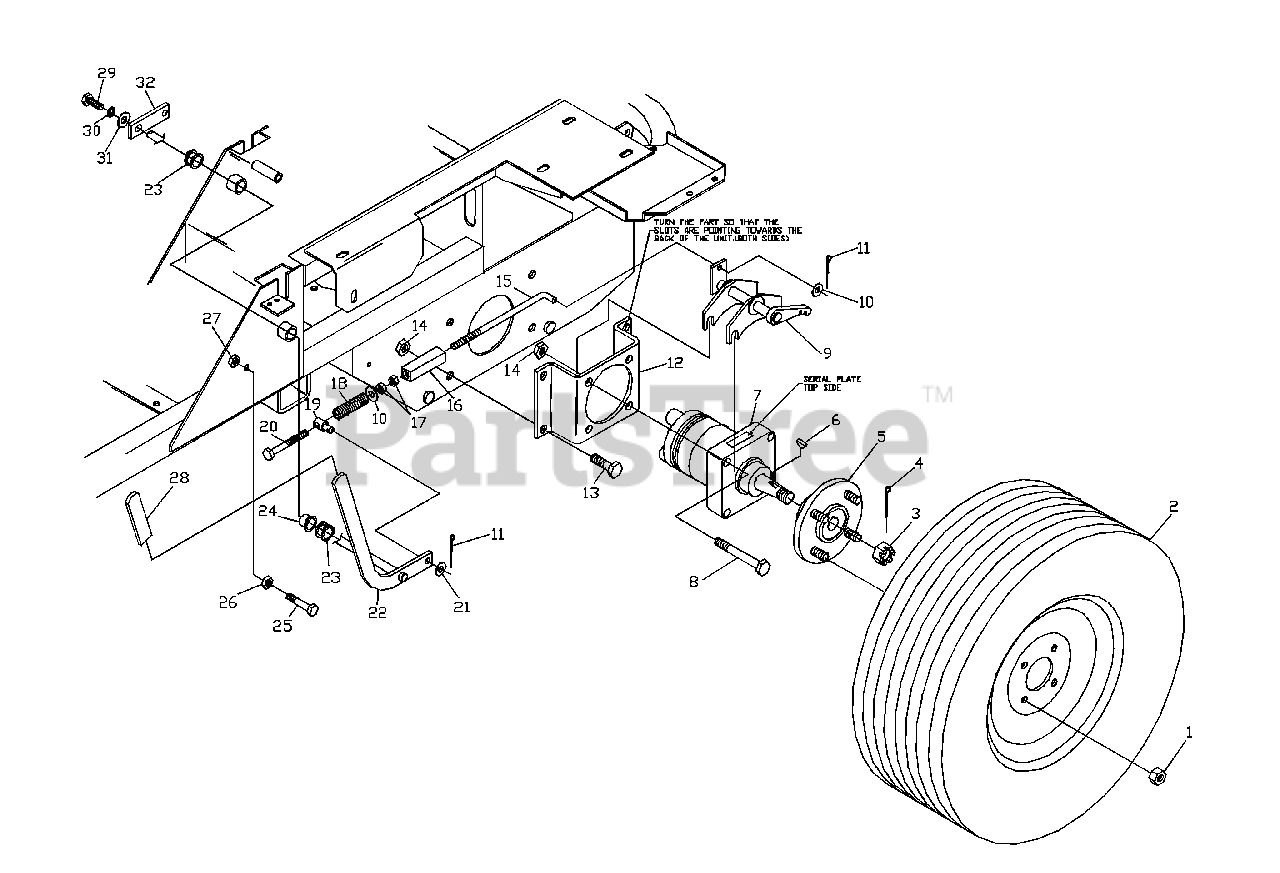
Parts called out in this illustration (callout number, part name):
1	LUG NUT 1/2F
2	REAR TIRE ASM. (COMPLETE)
2	VALVE STEM
3	HEX SLOTTED NUT
4	COTTER PIN
5	HUB, W/SPROCKET
6	KEY, #808 WOODRUFF
7	WHEEL MOTOR
8	HCS 1/2C X 2 3/4
9	BRAKE WELDMENT LEFT
10	WASHER 5/16 FLAT
11	1/8 X 3/4 COTTER PIN
12	MOTOR STANDOFF
13	HCS 1/2C X 1 1/4 SERRATED HEAD
14	NUT 1/2C NYLOC
15	BRAKE LINKAGE
16	TURNBUCKLE
17	5/16C HEX NUT
19	BRAKE SWIVEL
20	HCS 5/16C, SPECIAL
21	3/8 SAE WASHER
22	PIVOT SHAFT
23	7/16" DISC SPRING WASHER
25	HCS 3/8C X 1 3/4
26	3/8C WHIZ NUT
27	NUT 3/8C CENTERLOCK
29	HCS 1/4C X 5/8
30	LOCK WASHER
31	WASHER 1/4 FLAT
32	ARM, PARK BRAKE
